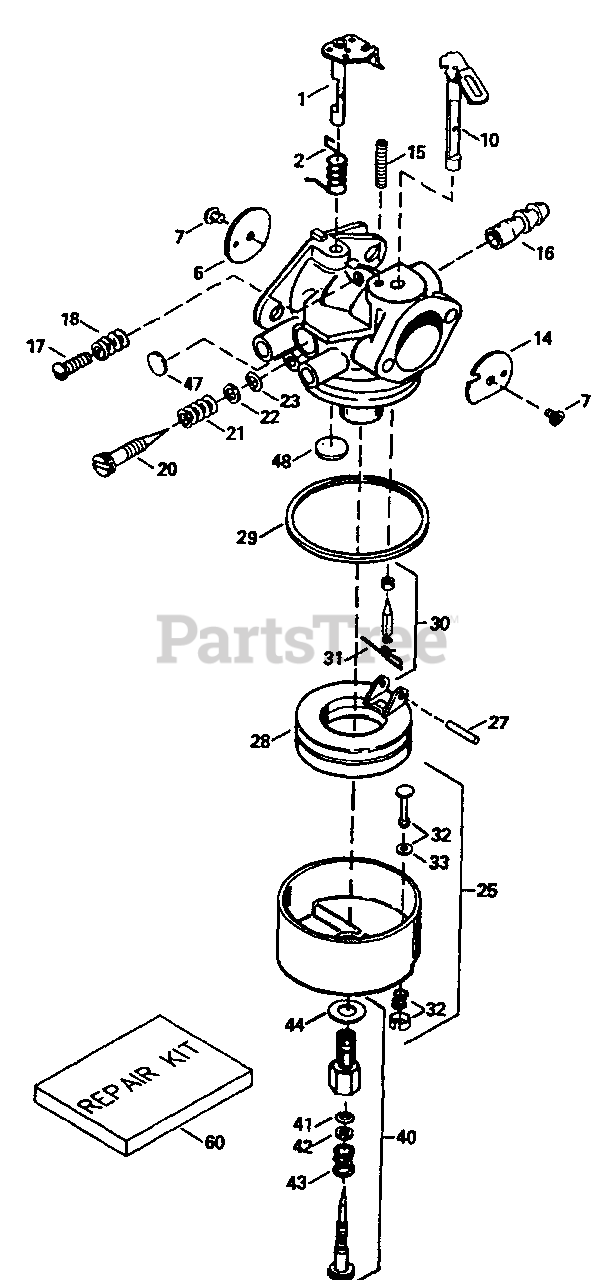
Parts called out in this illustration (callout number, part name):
1	Throttle Shaft & Lever Ass'y.
2	Throttle Return Spring
6	Throttle Shutter
7	Throttle & Choke Shutter Screw
10	Choke Shaft & Lever Ass'y.
14	Choke Shutter
15	Choke Positioning Spring
16	Fuel Fitting
17	Idle Speed Screw
18	Tension Spring
20	Idle Mixture Screw
21	Idle Tension Spring
22	Washer, Idle Screw
23	O-Ring, Idle Screw
25	Float Bowl Ass'y.
27	Shaft, Float
28	Float
29	O-Ring, Float Bowl to Body
30	Inlet Needle, Seat & Clip
31	Spring Clip
32	Bowl Drain Ass'y.
33	Drain Plunger Gasket
40	Main Adj. Screw Ass'y.
41	O-Ring, High Speed Mixture Screw
42	Washer, High Speed Mixture Screw
43	Tension Spring, High Speed Mixture Screw
44	Bowl Nut Washer
47	Welch Plug, Idle Mixture Well
48	Welch Plug, Atmospheric Vent
60	Repair Kit
